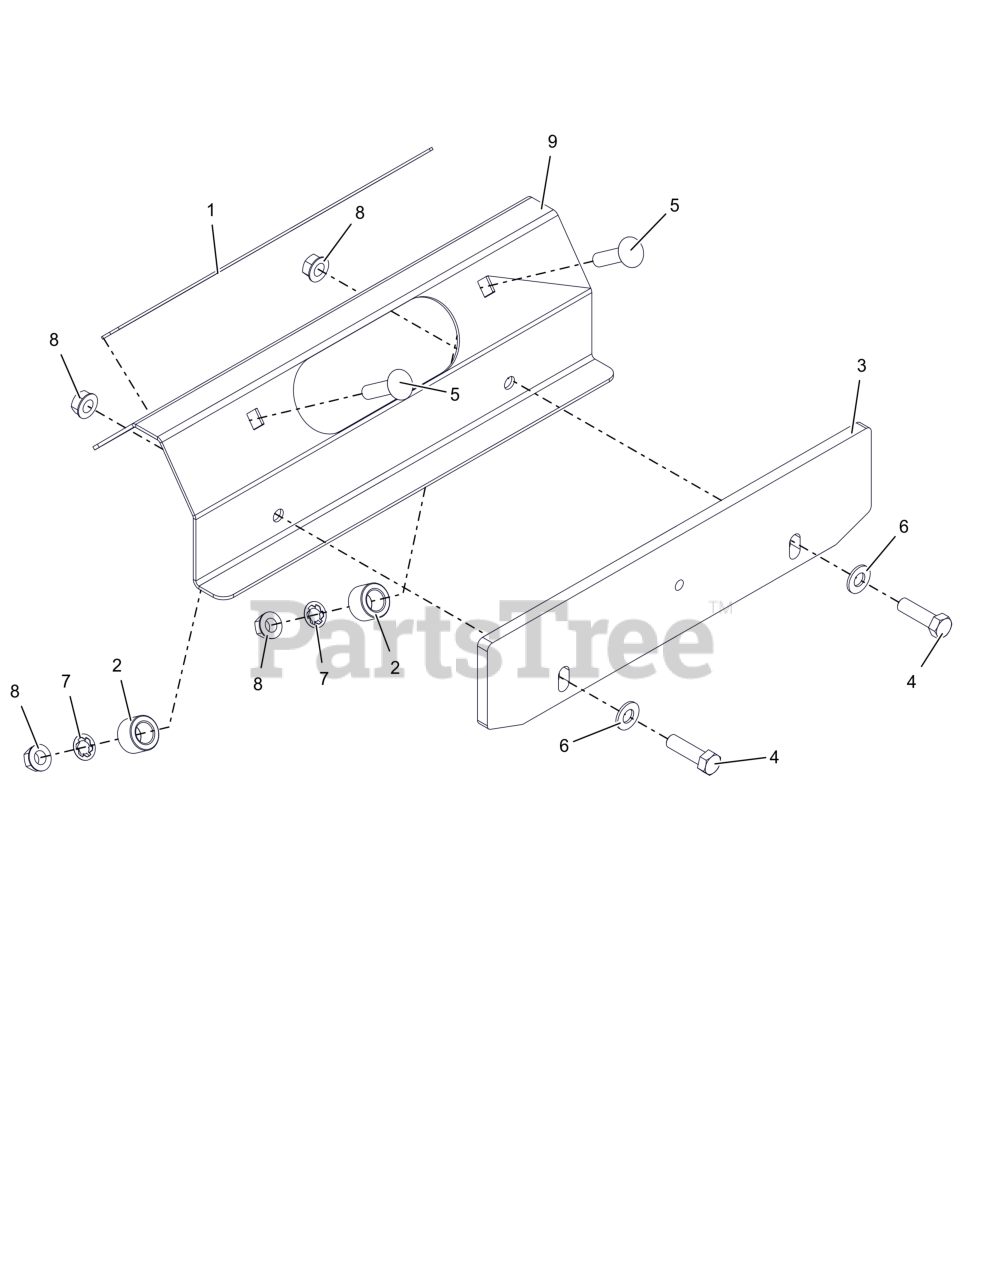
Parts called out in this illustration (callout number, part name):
1	GRIP, ADHESIVE (1" X 16" BLK)
2	TUBE, UPPER CONTROL PIVOT
3	PLATE, COUNTER WEIGHT
4	BLT, HEX .50-13X1.75 G5 ZCC
5	BLT, RHSN .50-13X2.00 G5 ZCC
6	WSHR,FLT .531X1.062X.095 ZCC
7	NUT-PUSH, .50
8	NUT-LK-CTR-FLG .500-13 GG ZCC
9	BRKT, BAGGER WEIGHT KIT (BLACK)
